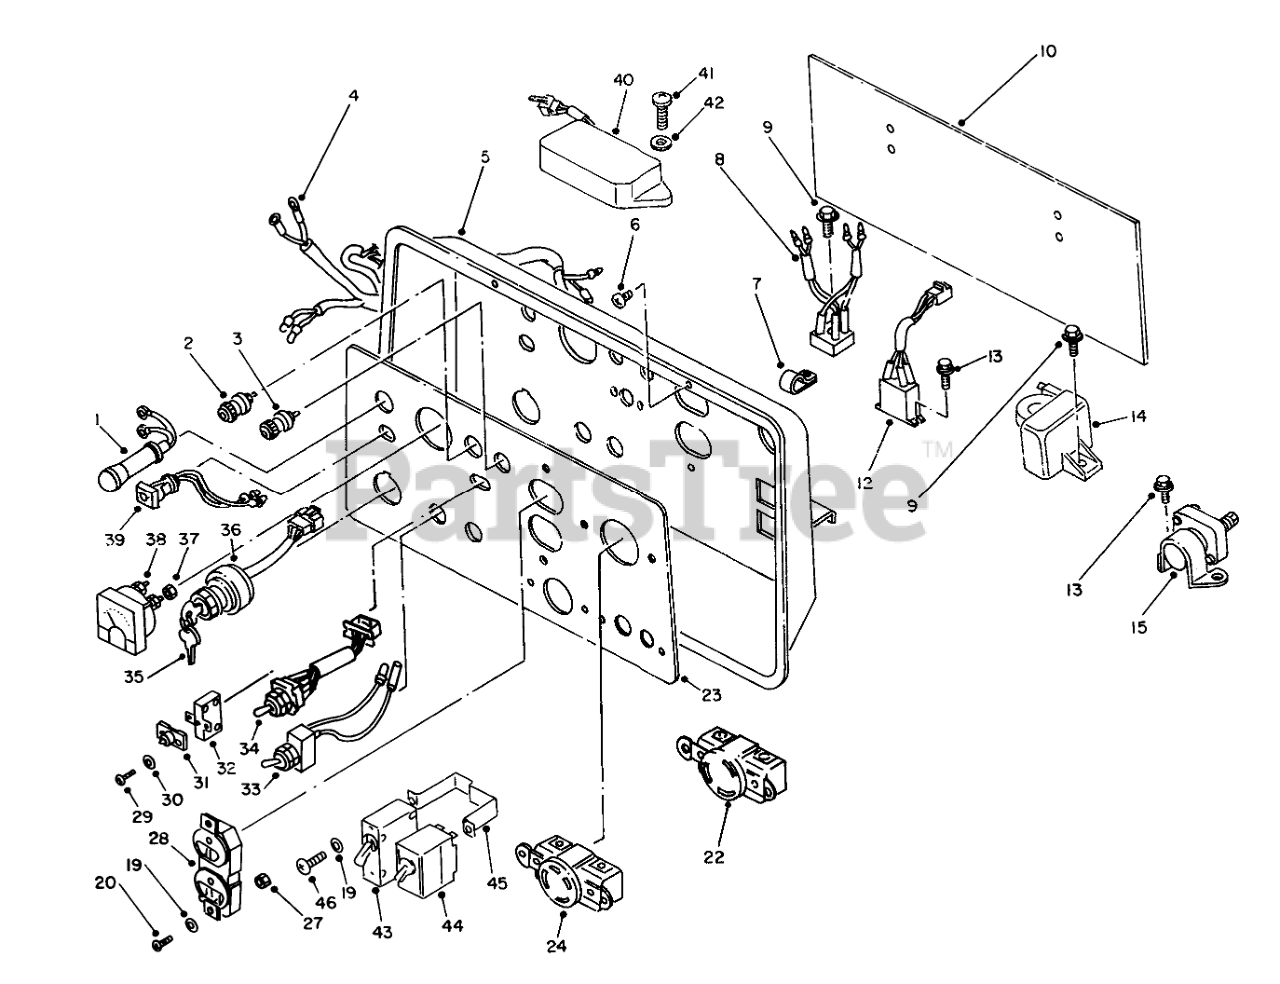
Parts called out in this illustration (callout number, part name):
1	Holder Assembly Lamp
2	TERMINAL (-)
3	Terminal
4	Harness-Control (110V/220V)
5	Panel-Control
6	Screw
7	Clamp
8	RECTIFIER ASM
10	Insulato Panel
12	Relay
13	SCREW-HHF
14	Unit-Slow Down
15	RELAY ASM
19	Washer
22	Receptacle (125V, 30A)
23	Plate-Panel
24	Receptacle
28	Receptacle
29	Screw
30	Washer
32	Circuit Breaker DC
33	Switch-Auto Idle
34	Switch-Remote Select
36	Switch Assembly-Engine (Incl. Ref. #35)
38	Meter-Voltage(150V/300V)
39	Lamp-Oil Level
40	Unit-Fuel/Oil Interlock
41	Screw
42	WASHER
43	Breaker-Circuit (30A)
44	Breaker-Circuit
45	Holder-Breaker
46	Screw
